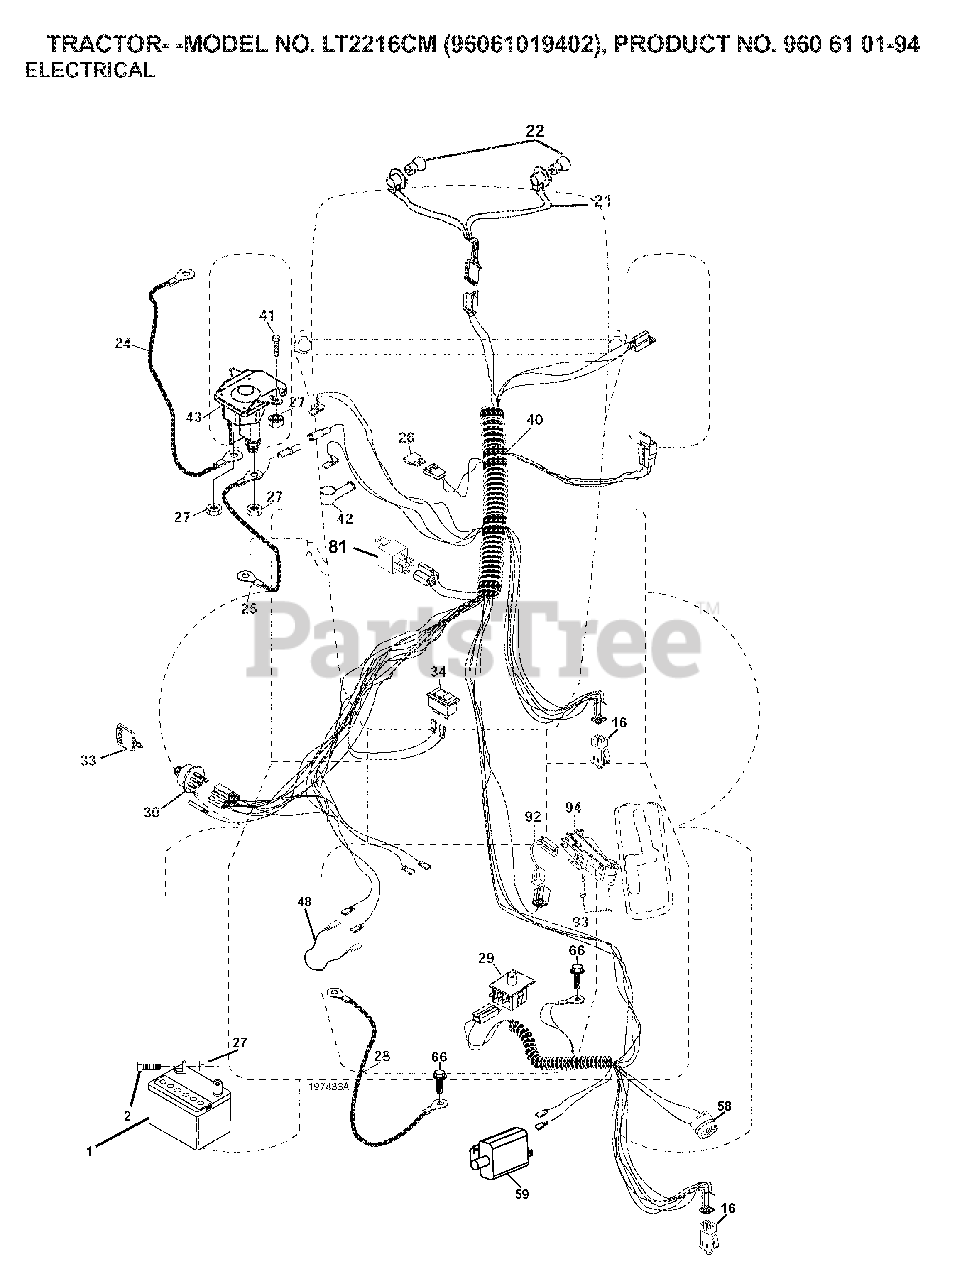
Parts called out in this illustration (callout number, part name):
1	BATTERY 12V .35 AMP
16	SWITCH INTERLOOK PUSH-IN
21	HARNESS ASSY LIGHT
22	LIGHTBULB
24	BATTERY CABLE GT
25	CABLE BATTERY
26	FUSE 20AMP
27	NUT
28	CABLE GROUND
29	SWITCH.SEAT.DP W/RAMPS
30	SWITCH.IGN.DELTA.W.LGH.ROS
33	KEY MLD GEN DELTA
34	SWITCH LT
42	TERMINAL COVER
43	SOLENOID.W/BRASS.PLUNG
58	BUZZER
81	RELAY.ASSY.T
92	HARNESS.PIGTAIL.CONSLE
93	SCREW.PLASTITE
94	MODULE.REVERSE.ROS
